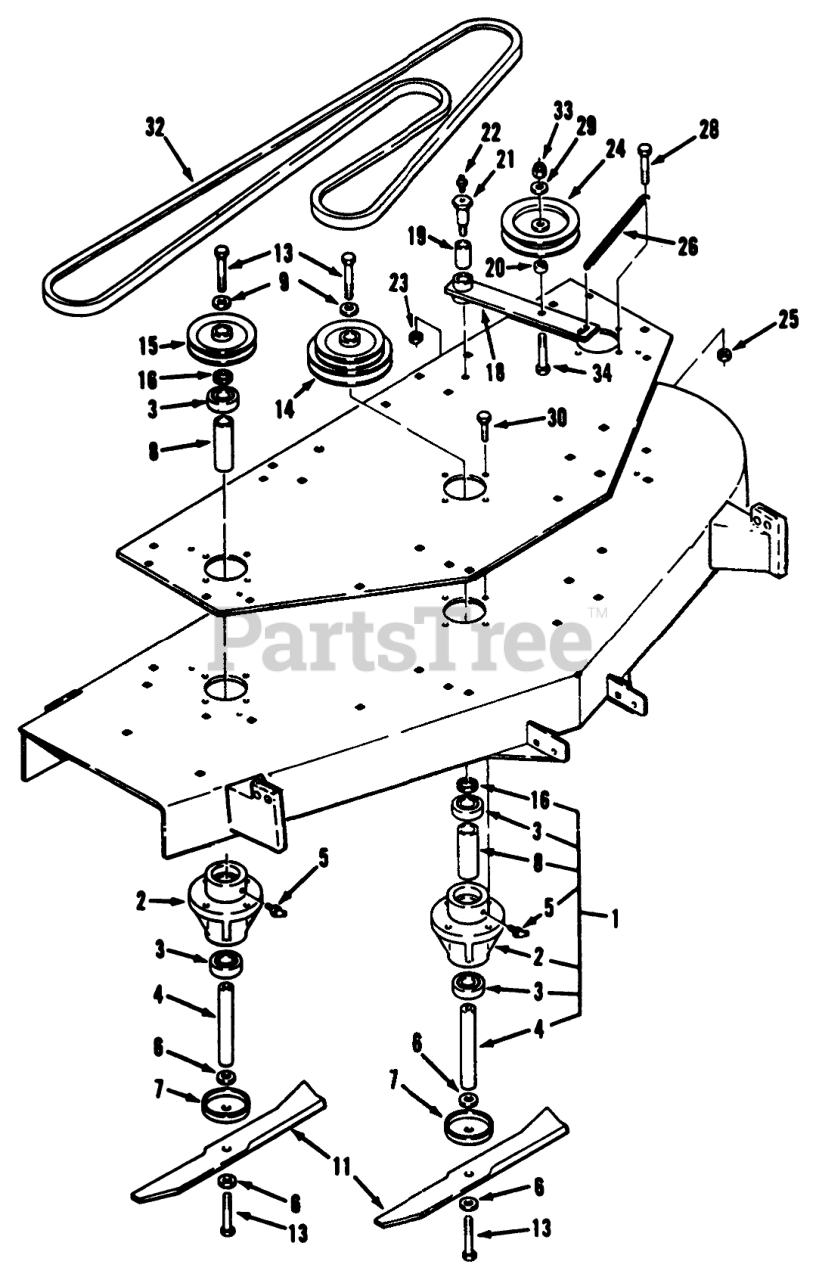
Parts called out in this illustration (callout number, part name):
1	S/A COMM MWR SPINDLE
2	HOUSING-SPINDLE
3	BEARING-BALL
4	SHAFT-SPINDLE
5	FITTING-GREASE
6	WASHER-SPECIAL
7	CUP-SPINDLE
9	WASHER-SPECIAL
11	BLADE
13	Bolt
14	Pulley-Center Spindle
15	PULLEY-OUTER
16	SPACER
18	Idler Arm Assembly (Incl. Ref. #19)
19	BUSHING
20	SPACER
21	BOLT-SHOULDER
22	FITTING-GREASE, 90 DEG
23	NUT-LOCK, NI
24	PULLEY-IDLER
25	NUT-JAM
26	SPRING-EXTENSION
28	SCREW-HH
29	WASHER-FLAT
30	SCREW-HH, LOCK
32	BELT-V
33	NUT-LOCK, NI
34	SCREW-HH
